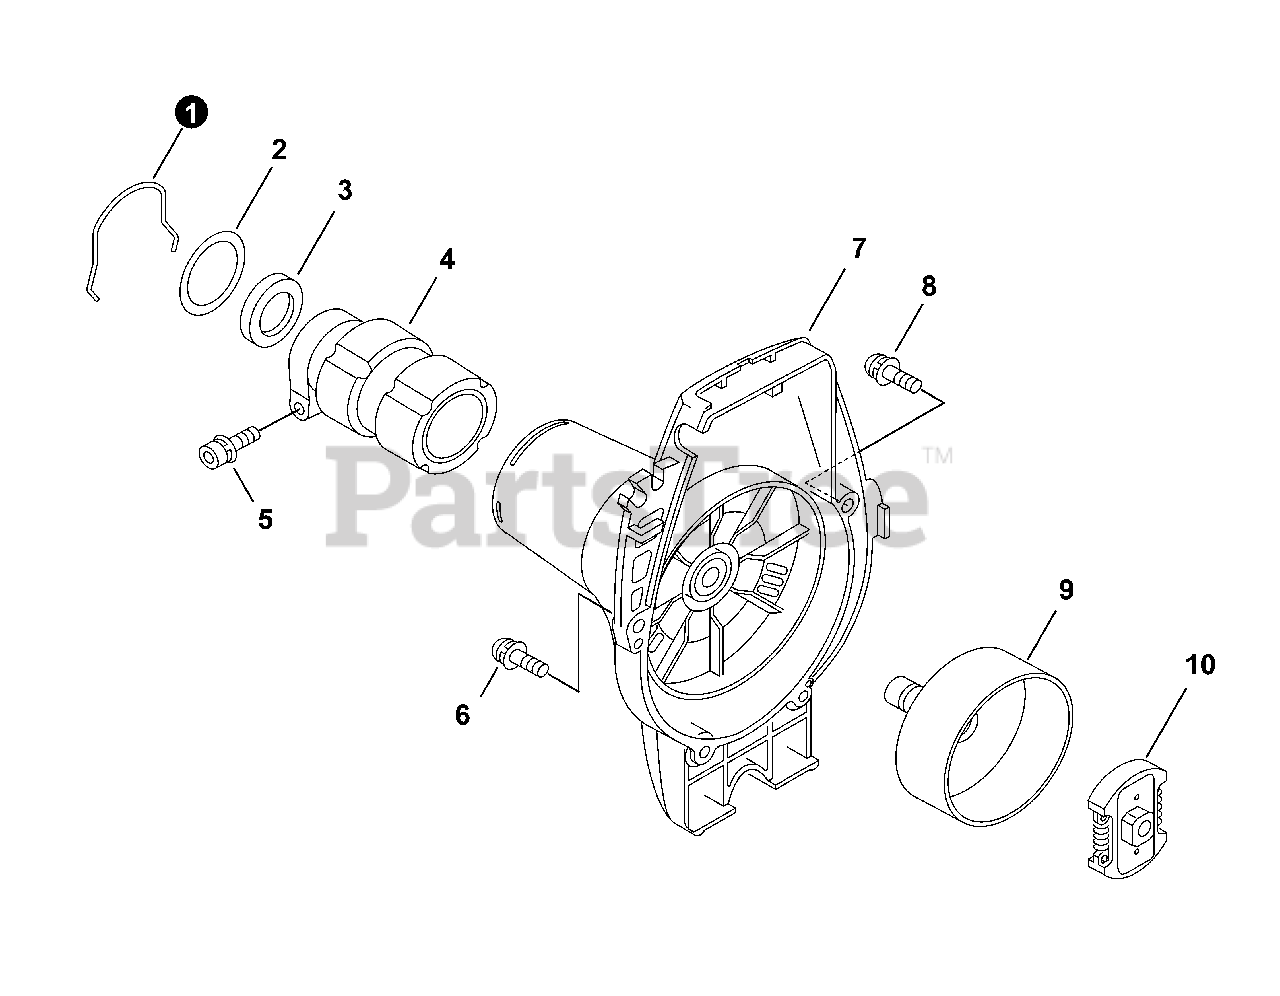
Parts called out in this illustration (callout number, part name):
2	WASHER 33.5×41.0×T0.5
3	PACKING, FELT
4	HOLDER, MAIN PIPE
5	BOLT 5×28
6	SCREW 4×16
7	COVER, FAN
8	SCREW 4×16
9	DRUM, CLUTCH
10	CLUTCH ASSY
